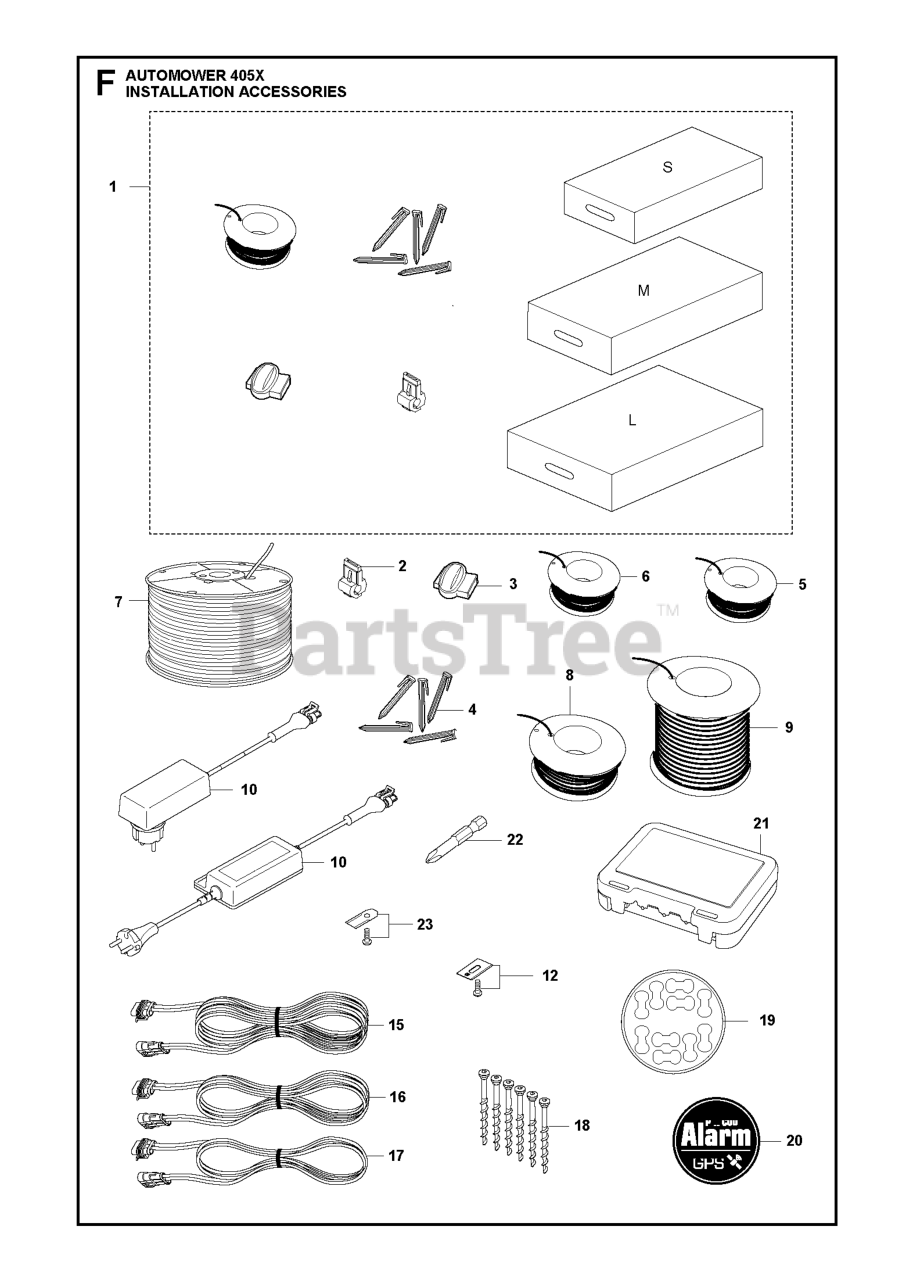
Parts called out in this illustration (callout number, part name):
1	LARGE AUTOMOWER INSTALL KIT
2	CONNECTOR 100 PCS
2	BRAKER
2	CONNECTOR 5 PCS, BLISTER
3	SPLICE KIT
3	COUPLER SPLICER, 100 PCS
3	COUPLER SPLICER, 5 PCS,
4	STAPLE 100 PCS, BLISTER
5	WIRE 50M STANDARD Ø2.7MM,BLIST
5	WIRE 150M, BLISTER
6	WIRE 250M
9	WIRE (800M)
10	POWER UNIT POWER SUPPLY 1,3A
10	Power Unit
15	CABLE ASSY LOW VOLTAGE CABLE
16	CABLE ASSY LOW VOLTAGE CABLE
17	CABLE ASSY LOW VOLTAGE CABLE
18	Screws
19	STICKER CABLE MARKERS KIT 10PC
20	Decals
21	CONNECTOR PROTECTION BOX
22	WRENCH BITS CHANGING ROBOTIC B
23	HUS BLADE SET 9 PCS
23	HUS BLADE SET 45 PCS
23	HUS BLADE SET 300 PCS
